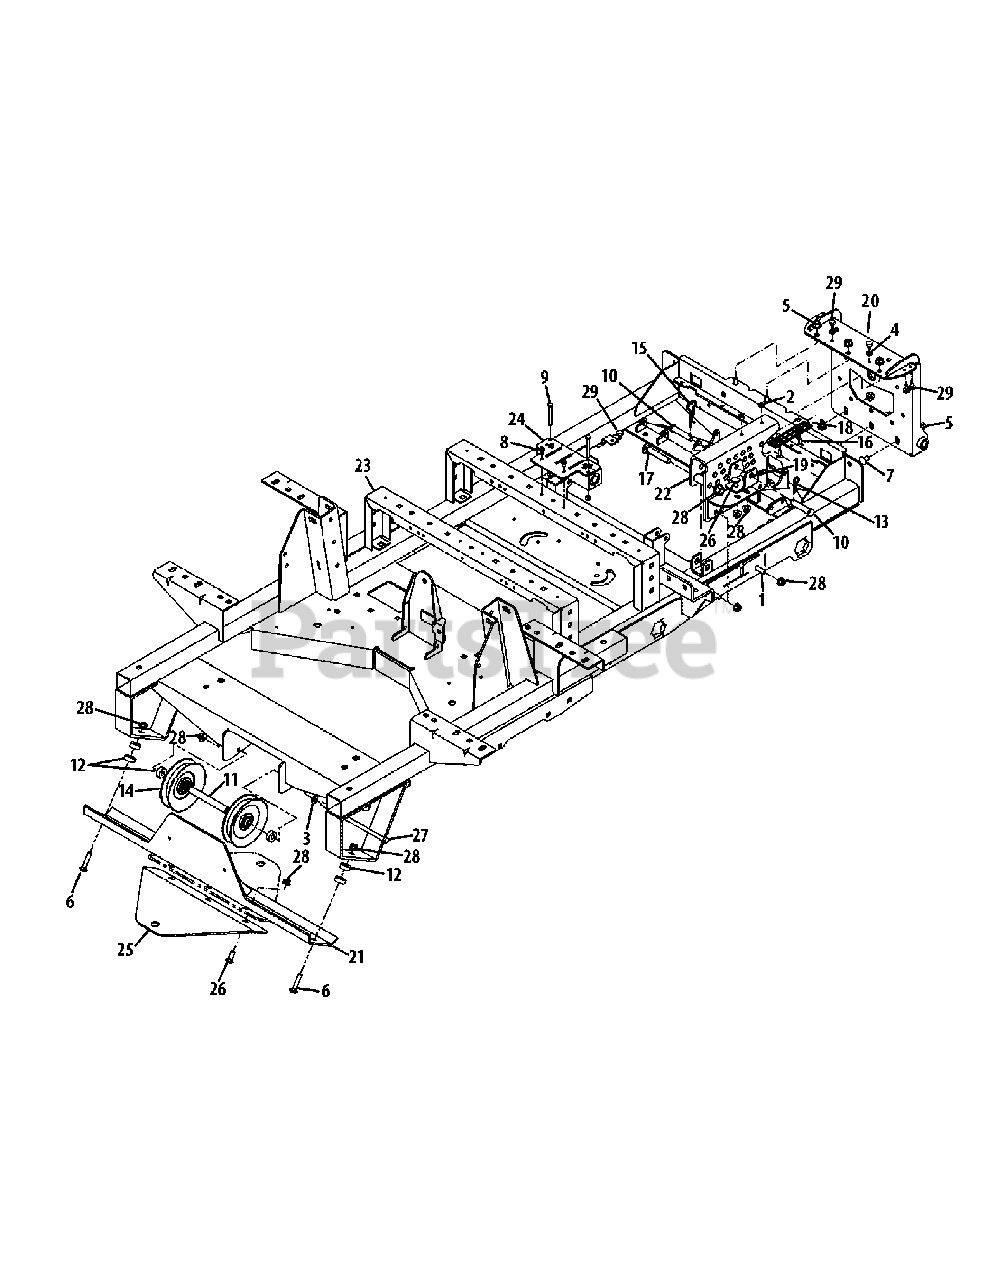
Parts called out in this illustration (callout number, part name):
1	Carriage Bolt, 3/8-16 x 1.25
2	Nut, 1/4-20
3	Washer, .406 x .813 x .063
4	Washer, .344 x .688 x .063
5	Flange Counter Lock Nut, 3/8-16
6	Carriage Bolt, 3/8-18 x 1.75
7	Carriage Bolt, 3/8-16 x .75
8	Hex Flange Screw, 1/4-20 x .500
9	Hex Screw, 1/4-20 x 2.25
10	Clevis Pin, 1/2 x 2.500
11	Spacer, .385 x .75 x 4.89
12	Spacer, .406 x 1.00 x .38
13	Hair Pin, 1/2 x 1.625 x .125
14	Idler Pulley
15	Hitch Pin, .120 x 3.00
16	Flat Head Screw, 1/4-20 x .750
17	Carriage Bolt, 1/2-13 x 3.00
18	Wear Plate, 1.125 x 5.0
19	Cylinder Mount Bracket
20	Front Axle Bracket Assembly
25	Hitch Bracket
26	Carriage Bolt, 3/8-16 x 1.00
27	Hex Screw, 3/8-16 x 8.50
28	Flange Lock Nut, 3/8-16
29	Rubber Bumper, .62 x .22
